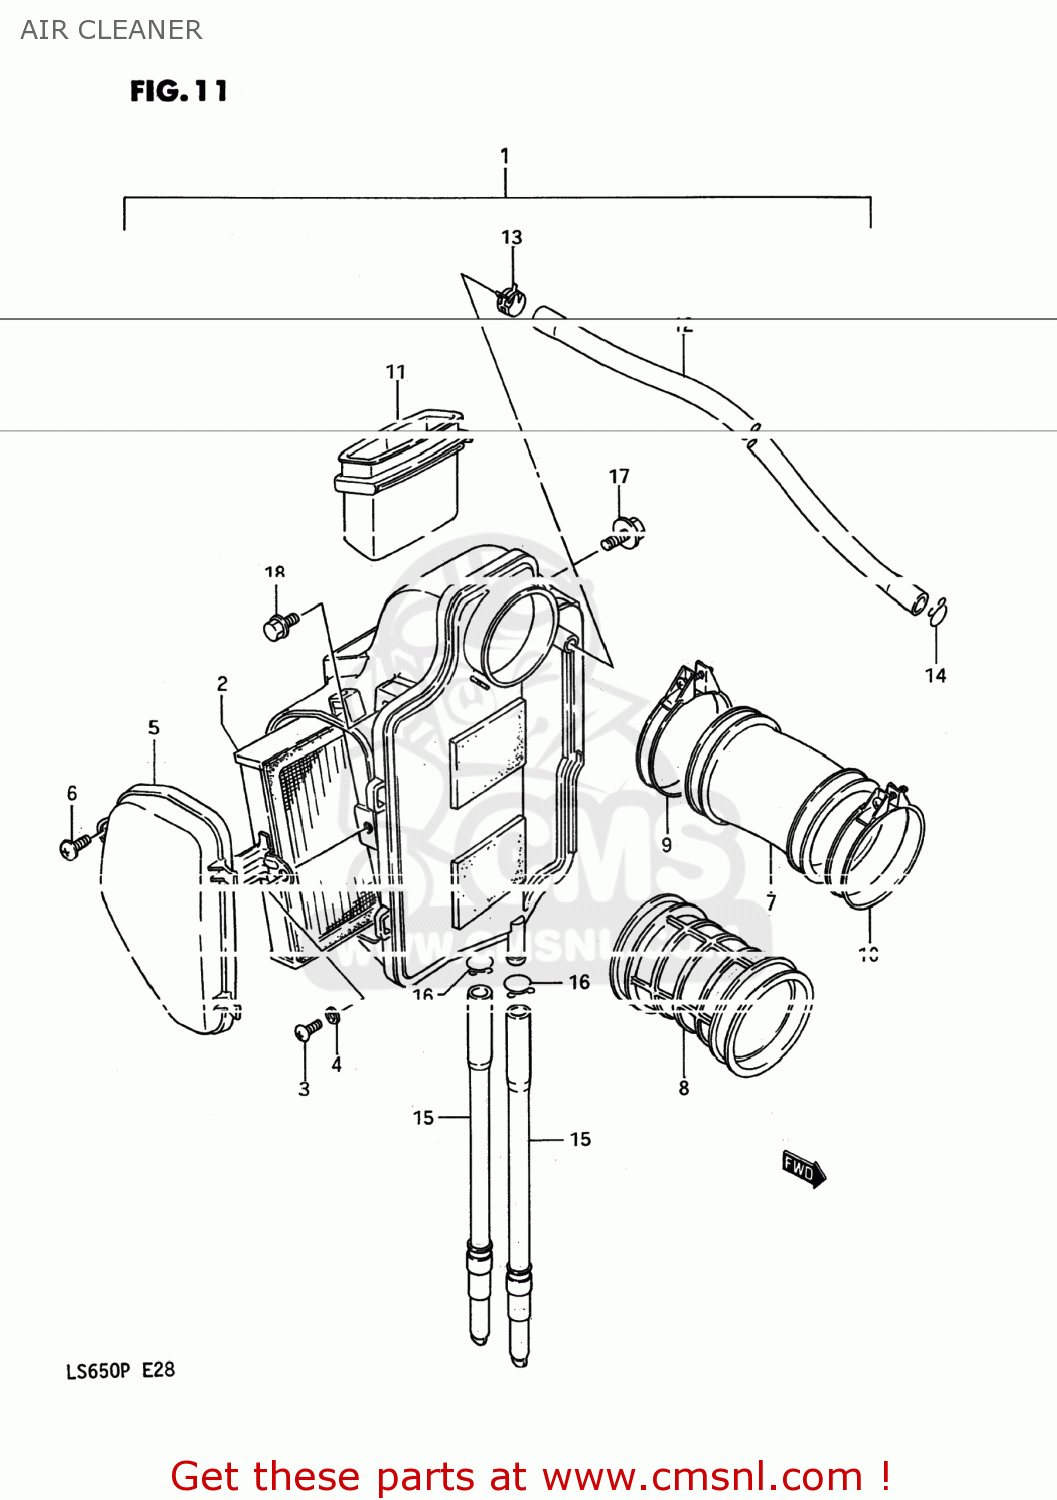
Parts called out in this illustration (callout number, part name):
1	CLEANER ASSEMBLY,AIR
2	FILTER ASSY,AIR
3	SCREW
4	LOCK WASHER
5	CAP,AIR CLEANER
6	SCREW, FRONT & REAR
7	TUBE,AIR CLEANER OUTLET
8	TUBE,AIR CLEANER OUTLET
9	CLAMP
10	CLAMP
11	TUBE,INLET
12	TUBE,BREATHER
13	CLIP
14	CLIP
15	DRAIN TUBE
16	CLIP
17	BOLT
18	BOLT 6X12
